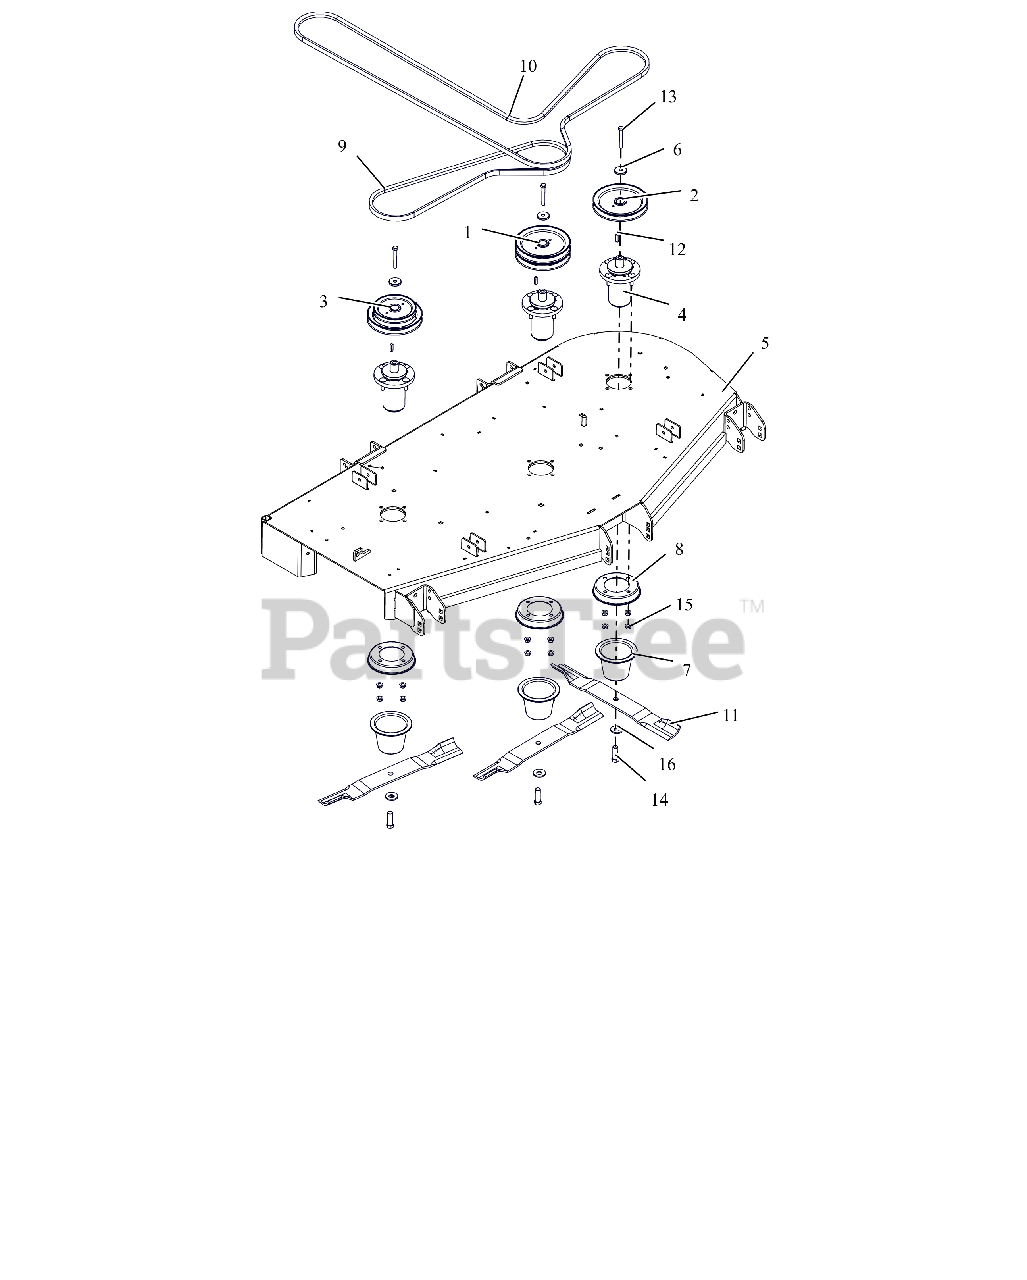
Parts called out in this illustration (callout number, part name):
1	PULLEY, DOUBLE-1"ID X 6.75"OD
2	PULLEY, V-1" ID X 6.75" OD
3	PULLEY, DBL-1"IDX6.75"&5.25"OD
4	ASM, MAINT FREE ALUM SPINDLE
5	60"SIDE DISCH DECK WMT W/SAFE
6	RETAINER, SHEAVE
7	GUARD, SPINDLE LOWER
8	GUARD, SPINDLE TOP
9	V-BELT, B-COGGED
10	V-BELT, HB-WRAPPED
11	BLADE, MOWER (20.50")
12	KEY, SQ .25X.25X1.00 RC 40-50
13	BLT, HEX .38-16X2.75 G8 ZCC
14	BLT, HEX .62-18X1.75 G8 ZCC
15	NUT-LK-CTR-FLG .375-16 GF ZCC
16	WSHR-BLVL .669X1.535X.138
